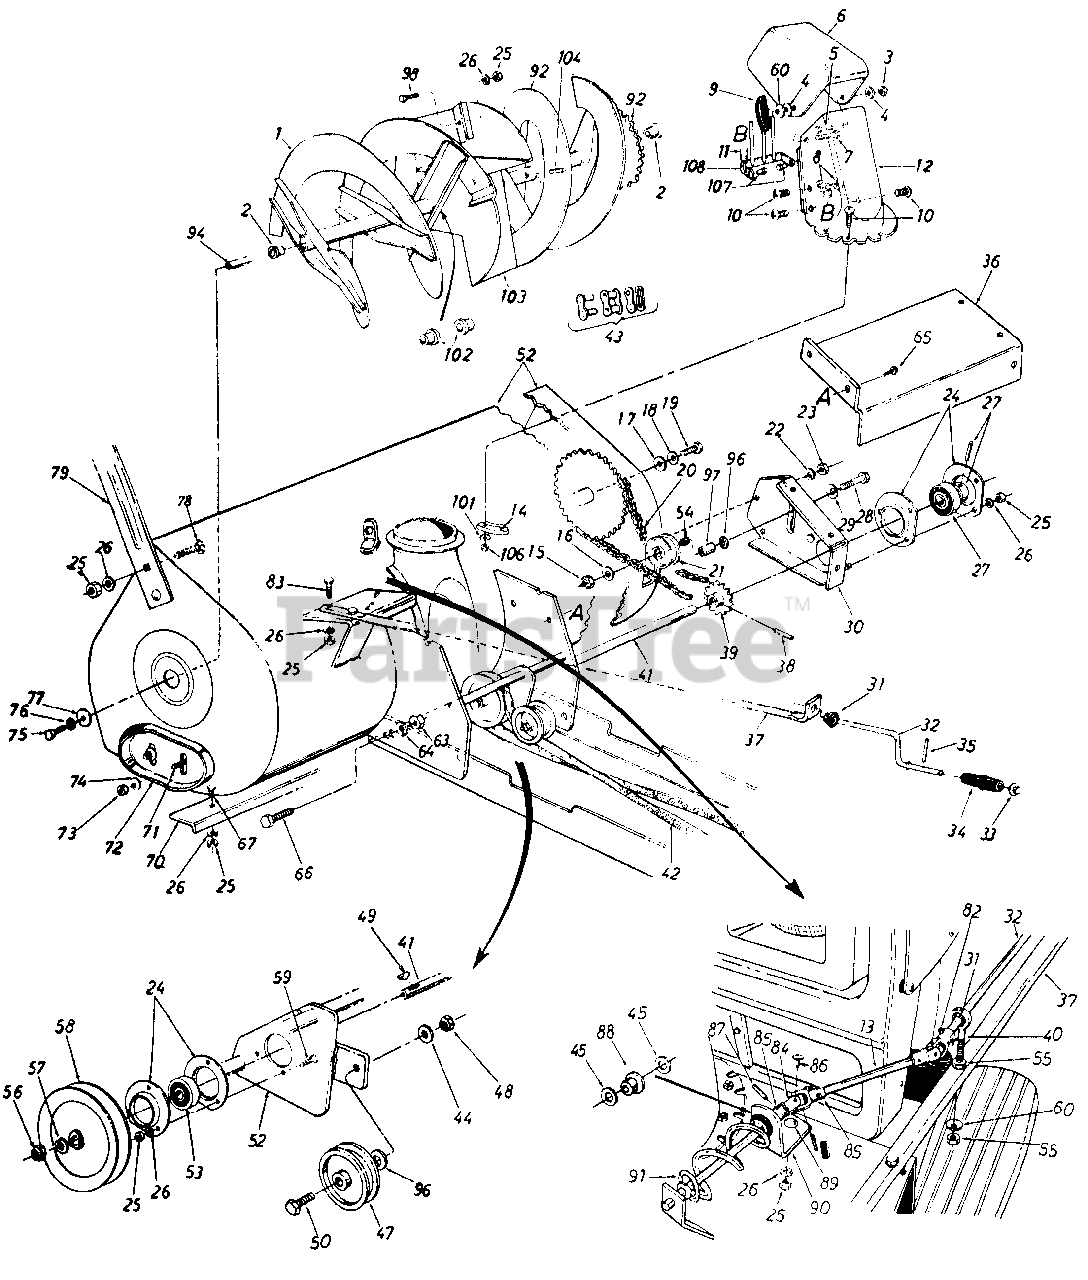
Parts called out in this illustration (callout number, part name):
1	Spiral Ass'y. (L.H.)
2	Flange Bearing
3	Hex Cent. L.-Nut 5/16-18 Thd.
4	Fl.-Wash. .344" I.D.
5	Truss Mach. Scr. 5/16-18 x .75" Lg.
6	Upper Chute
7	Carriage Bolt 5/16-18 x 1.0" Lg.
8	Hex L-Nut 1/4-20 Thd.
9	Hand Knob
10	Truss Mach. Scr. 1/4-20 x .75" Lg.
11	Ext. Spring
12	Lower Chute
13	Chute Crank Extension Rod
14	Chute Flange Keeper
15	L.-Nut 3/8-16 Thd.
16	Fl.-Wash.
17	Fl.-Wash.
18	Belleville Wash.
19	Hex Bolt 1/2-13 x 1.00" Lg.*
20	#420 Chain 1/2" Pitch x 77 0 Links
21	Plastic Idler 2.00" O.D.
22	L.-Wash. 1/4" I.D.*
23	Hex Nut 1/4-20 Thd.4
24	Bearing Housing
25	Hex Nut 5/16-18 Thd.*
26	L.-Wash. 5/16" I.D.*
27	Self-Aligning Bearing
28	Hex Bolt 3/8-16 x 1.75" Lg.*
29	Belleville Wash. 3/8" I.D.
32	Chute Crank .375 Dia. x 34.5" Lg.
33	Push Nut 3/8" Rod
34	Knob (Black)
35	Roll Pin
39	14 Teeth Sprocket Ass'y.
40	Eyebolt 5/16-18 x 3.0" Lg.
41	Drive Shaft
42	V Belt
43	Master Link for #420 Chain
44	L.-Wash. 3/8" I.D.*
45	Fl.-Wash. .385 I.D. x .62" O.D.
47	Fl.-ldler with Flanges
48	Hex Jam L.-Nut 3/8-16 Thd.
49	#61 Hi-Pro Key 3/16 x 5/8" Dia.
50	Hex Bolt 3/8-16 x 1.75" Lg.*
52	Spiral Housing Ass'y.
53	Self-Aligning Bearing
54	Sleeve Bearing .50" I.D.
55	Hex Nut 5/16-18 Thd.*
56	Hex Nut 3/4-10 Thd.
57	L.-Wash. 3/4" I.D.
58	VPulley .750" I.D. x 6.00" O.D.
59	Hex Sems Bolt 5/16-18 x .75" Lg.*
60	Bell-Wash. .345" I.D. x .88" O.D.
63	Hex Nut 1/2-13 Thd.*
64	L.-Wash. 1/2" I.D.*
65	Hex Wash. Hd. Tap Scr. 1/4-20 0 x .50" Lg.
66	Hex Bolt 1/2-13 x 2.75" Lg.*
67	Carriage Bolt 5/16-18 x .75"
72	Skid Shoe
73	Hex Jam Nut 3/8-16 Thd.
74	Belleville Wash. 3/8" I.D.
75	Hex Bolt 1/2-13 x 1.00" Lg.*
76	Belleville Wash. 1/2" I.D.
77	Fl.-Wash.
78	Carriage Bolt 5/16-18 x .62" Lg.
79	Drift Cutter
82	Cotter Pin
83	Hex Bolt 5/16-18 x 1.50" Lg.*
84	Joint Block
85	Joint Bracket Ass'y.
86	Oval Head Rivet
87	Spring Pin Roll 1/8" Dia. x .75" Lg.*
88	Nylon Bushing
89	Carriage Bolt 5/16-18 x .75" Lg.
90	Chute Crank Bracket
91	Chute Crank Ass'y.
92	Spiral Ass'y. (R.H.)
94	Spiral Axle
96	Flat Washer
97	Idler Spacer
98	Carriage Bolt 5/16-18 x .75" Lg.
101	Fl.-Wash. 1/4" I.D.
102	Plastic Bushing
103	Rotor Paddle Ass'y.
104	Spring Pin Spir. 5/16" Dia. x 1.75" Lg.
106	Hex L.-Nut 1/4-20 Thd.
107	Shld. Nut 1/4-20 Thd.
108	Chute Guard Ass'y.
